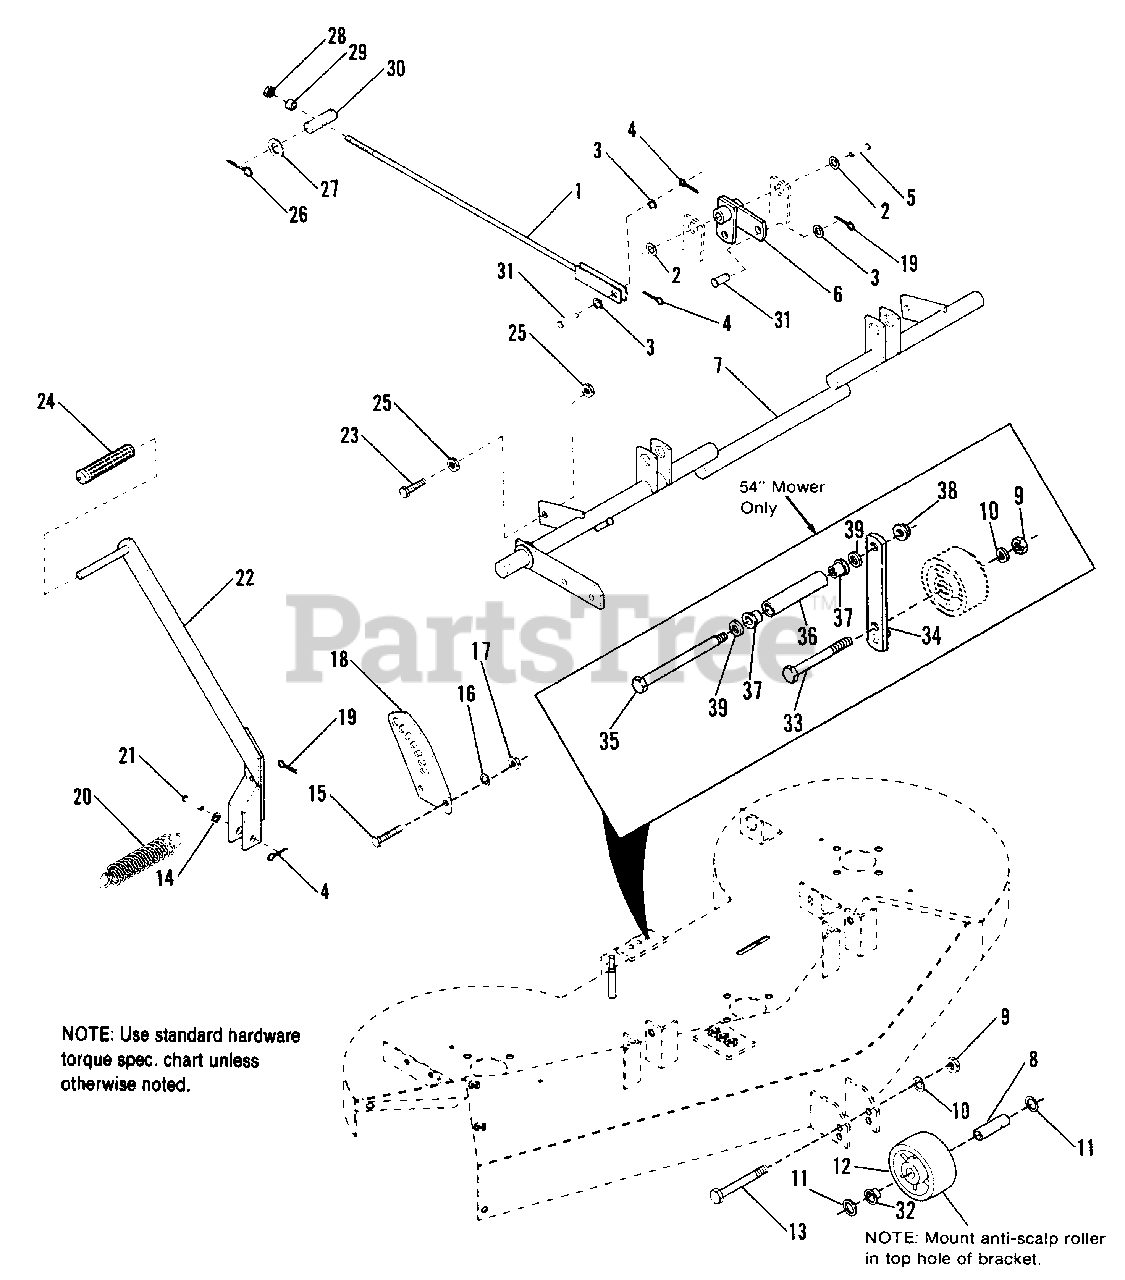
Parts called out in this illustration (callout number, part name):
1	ADJUSTING ROD ASSY. (46" Mower)
1	ADJUSTING ROD ASSY. (54", 60" & 66" Mower)
2	WASHER, Plain
3	WASHER, Plain
5	CLEVIS PIN, 1/2 x 2-3/4
6	HANGER ASSY.
7	SHAFT ASSY., Lift (46" Mower)
7	SHAFT ASSY., Lift (54" Mower)
7	SHAFT ASSY., Lift (60" Mower)
7	SHAFT ASSY., Lift (66" Mower)
8	SPACER (46" Mower)
8	SPACER (46", 54" & 60" Mower)
8	SPACER (46", 54", 60" & 66" Mower)
9	NUT, Hex, 1/2-13 (46" Mower)
9	NUT, Hex, 1/2-13 (46", 54" & 60" Mower)
9	NUT, Hex, 1/2-13 (46", 54", 60" & 66" Mower)
10	LOCKWASHER, Spring, 1/2 (46" Mower)
10	LOCKWASHER, Spring, 1/2 (46", 54" & 60" Mower)
10	LOCKWASHER, Spring, 1/2 (46", 54", 60" & 66" Mower)
11	WASHER, Plain (46" Mower)
11	WASHER, Plain (46", 54" & 60" Mower)
11	WASHER, Plain (46", 54", 60" & 66" Mower)
12	WHEEL, Gauge, 4" Dia. (46" Mower) (Incl. Ref. No. 32)
12	WHEEL, Gauge, 4" Dia. (46", 54" & 60" Mower) (Incl. Ref. No. 32)
12	WHEEL, Gauge, 4" Dia. (46", 54", 60" & 66" Mower) (Incl. Ref. 32)
13	CAPSCREW, Hex, 1/2-13 x 3-1/2 (46" Mower)
13	CAPSCREW, Hex, 1/2-13 x 3-1/2 (46", 54" & 60" Mower)
13	CAPSCREW, Hex, 1/2-13 x 3-1/2 (46", 54", 60" & 66" Mower)
14	WASHER, Plain
15	CAPSCREW, Hex, 3/8-16 x 1-1/4
16	LOCKWASHER, Spring, 3/8
17	NUT, Hex, 3/8-16
18	PLATE, Height Adjusting
19	COTTER HAIRPIN
20	SPRING, Extension
21	CLEVIS PIN, 1/2 x 2
22	HANDLE ASSY., Left
23	CAPSCREW, Hex, 3/8-16 x 1-1/2
24	GRIP, Handle
25	NUT, Hex, 3/8-16
26	COTTER PIN
27	WASHER, Plain
28	NUT, Fiber Lock, 3/8-16
29	SPACER (46" Mower)
29	SPACER (54", 60", 66" Mowers)
31	CLEVIS PIN, 1/2 x 1-1/4
32	BEARING (46" Mower)
32	BEARING (46", 54" & 60" Mower)
32	BEARING (46", 54", 60" & 66" Mower)
33	CAPSCREW, Hex Hd., 1/2-13 x 4 (54" Mowers only)
34	BRACKET, Roller (54" Mower only)
35	BOLT, Shoulder (54" Mower only)
36	TUBE, Pivot (54" Mower only)
37	BUSHING, Flanged (54" Mower only)
38	NUT, Flange Whizlock, 3/8-16 (54" Mower only)
39	WASHER, Plain
